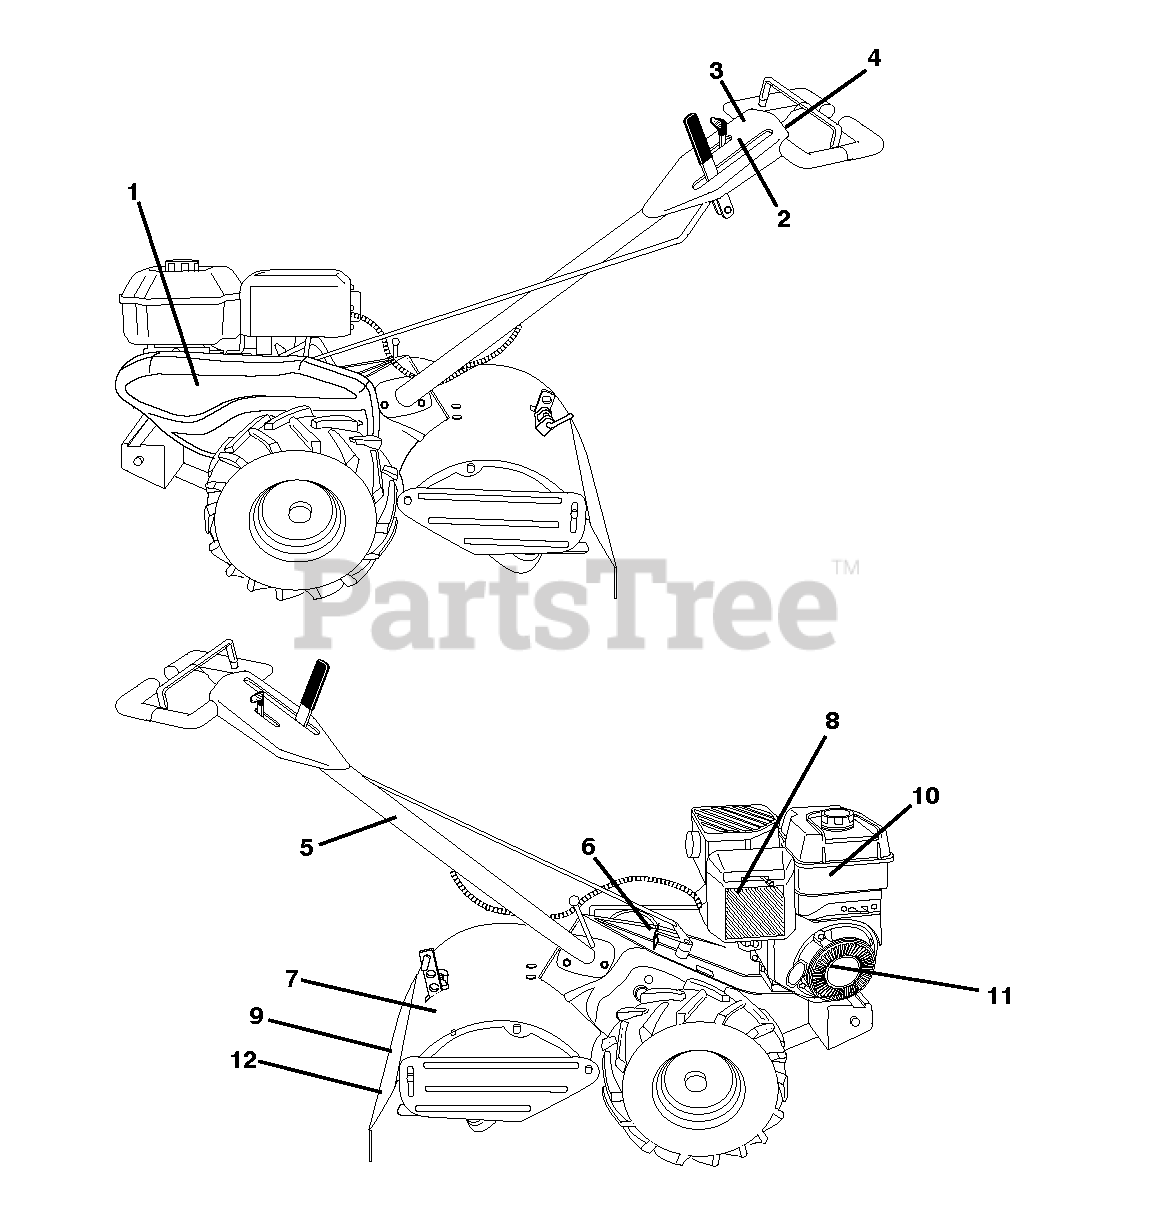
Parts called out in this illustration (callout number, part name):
6	DECAL.SHIFT.INDICATOR.TILLER
9	DECAL EUROPE STANDARD CE
11	DECAL, REWIND STARTER, B&S
